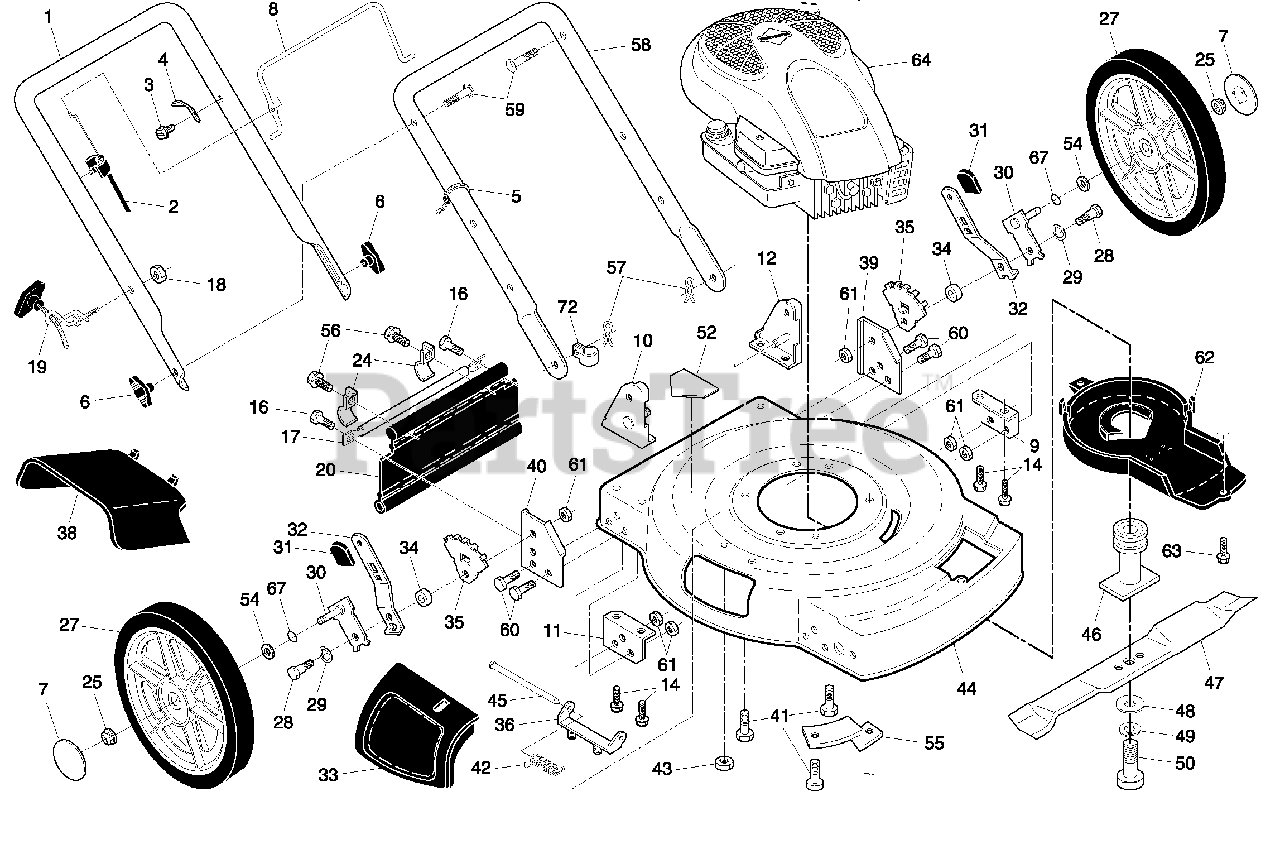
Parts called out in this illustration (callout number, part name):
1	Upper Handle
2	Engine Zone Control Cable
3	Screw
4	Bracket, Upstop
5	Wire Tie
6	Handle Knob
7	Hubcap
8	Control Bar
9	Support Bracket, Handle, LH
10	Handle Bracket, RH
11	Support Bracket, Handle, RH
12	Handle Bracket, LH
14	Screw, Thread Cutting 5/16-18 x 3/4
16	Screw
17	Support Rod
18	Locknut, Keps
19	Rope Guide
20	Rear Skirt
24	Clamp, Rear Skirt
25	Locknut, Hex 3/18-16
27	Wheel & Tire Assembly
28	Shoulder Bolt
29	Washer, Curved, Cylindrical
30	Axle Arm Assembly
31	Knob, Selector
32	Spring, Selector
33	Mulcher Door
34	Spacer
35	Bracket, Wheel Adjuster
36	Bracket, Housing
38	Deflector, Discharge
39	Support Bracket, LH
40	Support Bracket, RH
41	Screw, Hex Head, Threaded, Rolled 3/8-16 x 1-1/8
42	Spring, Torsion
43	Locknut, Hex
44	Kit, Lawn Mower Housing
45	Rod, Hinge
46	Blade Adapter / Pulley
47	Blade, 22"
48	Washer, Hardened
49	Washer, Lock, Helical
50	Screw, Hex Head, Grade 8 3/8-24 x 1-3/8
52	Decal, Danger
54	Washer, Flat
55	Mounting Bracket, Debris Shield
56	Screw, Hex Washer Head #10-24 x 1/2
57	Hairpin Cotter
58	Lower Handle
59	Handle Bolt
60	Bolt
61	Locknut, Hex
62	Debris Shield
63	Screw
67	O-Ring
72	Clip, Cable
72	Operator's Manual, English
72	Operator's Manual, French
72	Repair Parts Manual
